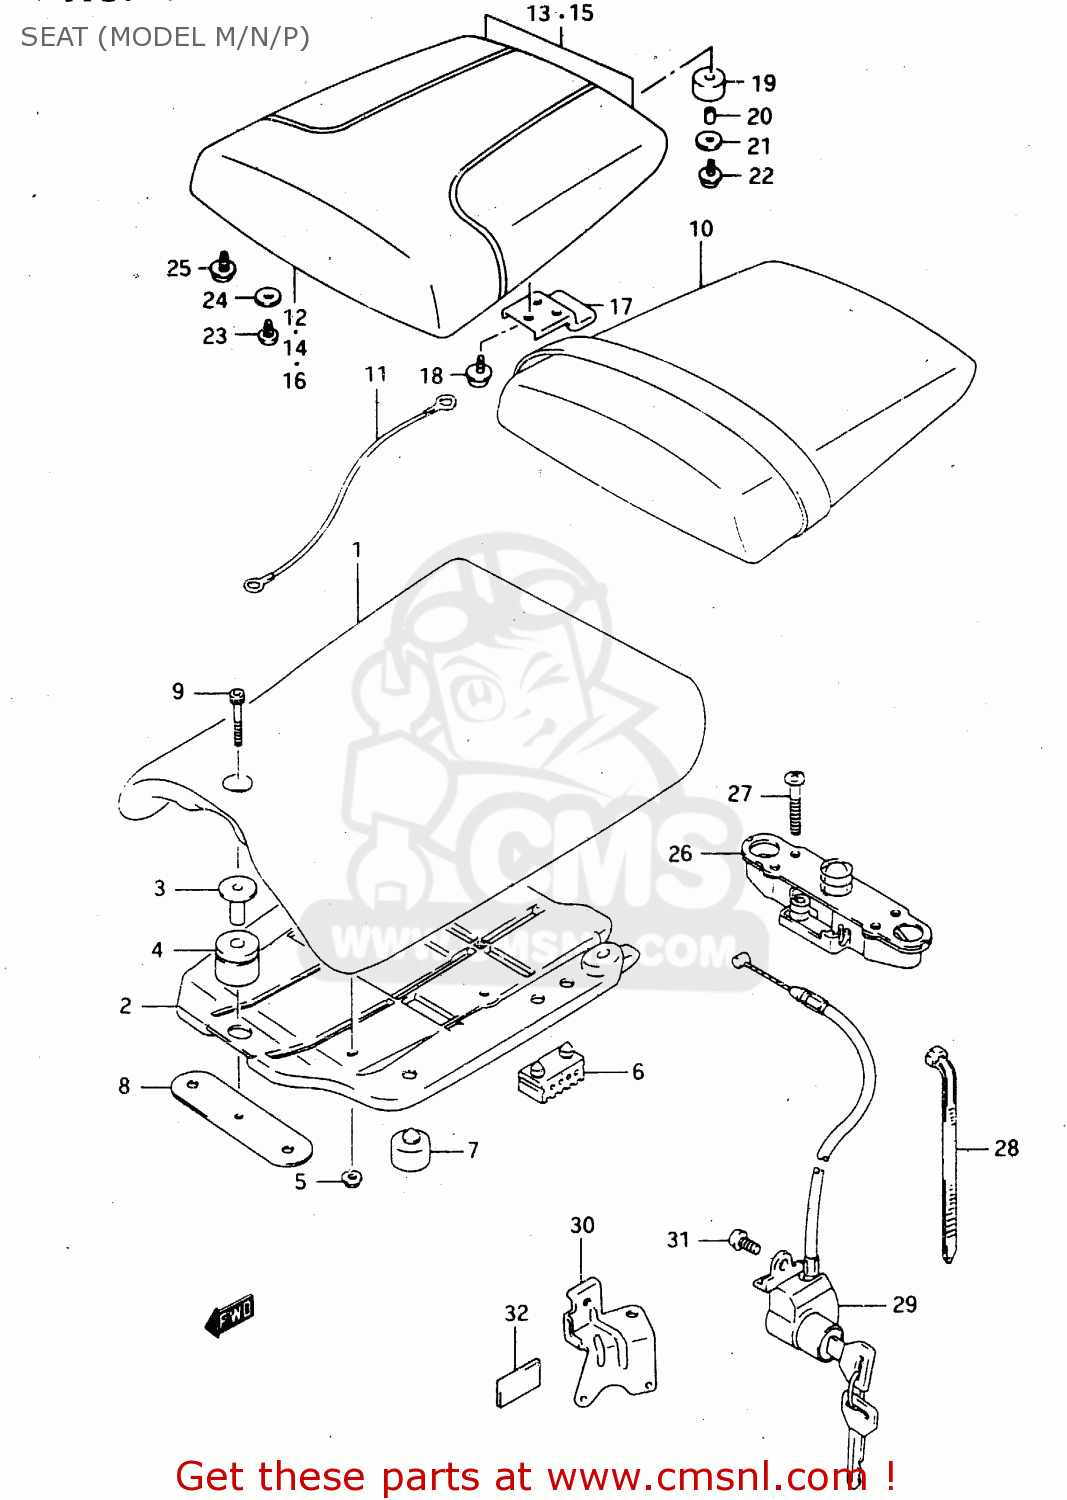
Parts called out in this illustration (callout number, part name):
1	SEAT ASSY
2	FRAME, SEAT BOTTOM
3	COLLAR,FR
4	CUSHION,SEAT
5	NUT
6	CUSHION,SEAT(40X20X15)
7	CUSHION
8	PLATE,SEAT FR
9	BOLT
10	SEAT ASSY, PILLION (BLACK)
11	CABLE,SEAT LOCK
12	BOX, SEAT TAIL (WHITE)
13	TAPE SET
14	BOX, SEAT TAIL (BLACK)
15	TAPE SET
16	BOX, SEAT TAIL (WHITE)
17	BRACKET
18	SCREW
19	CUSHION
20	SPACER (4.5X6.5X5)
21	WASHER(4.3X20X1.4)
22	SCREW
23	SCREW
24	WASHER (5.5X20X1.2)
25	SCREW
26	LOCK ASSY,SEAT STRIKER
27	SCREW
28	CLAMP L:165
29	LOCK SET,SEAT
30	BRACKET, SEAT LOCK
31	SCREW
32	MUD GUARD,REAR FENDER
